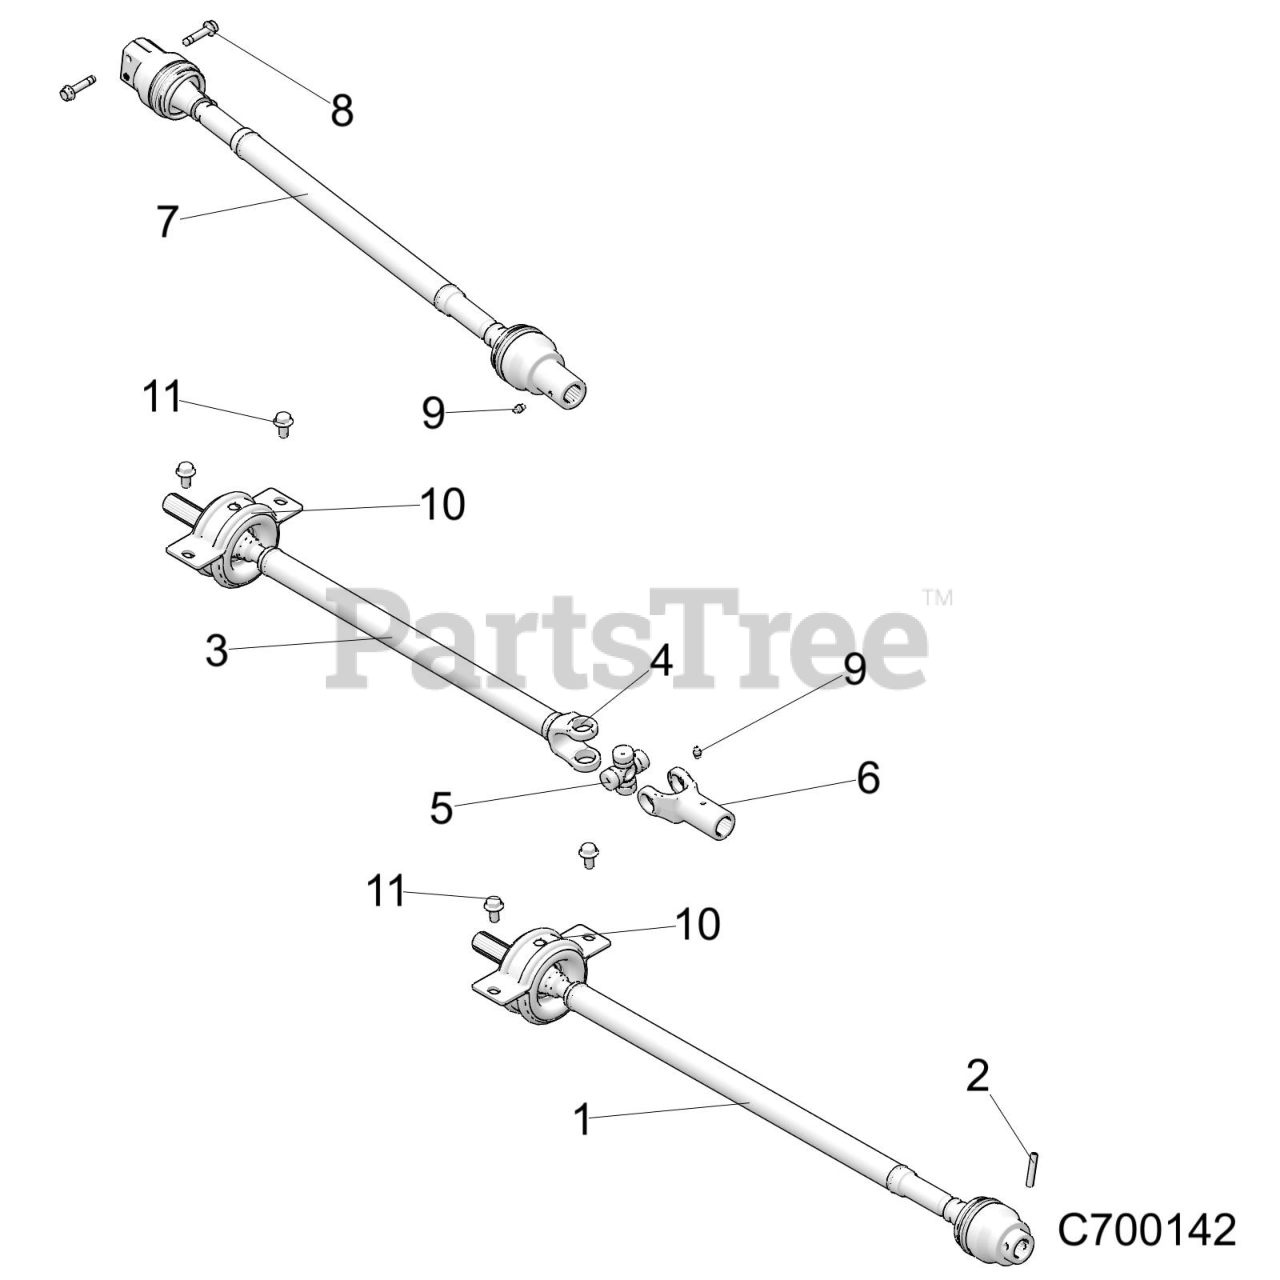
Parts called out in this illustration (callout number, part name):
1	ASM., PROPSHAFT, FRONT
1	ASM-PROPSHAFT,FRONT
2	PIN,SPRING(10)
3	ASM-PROPSHAFT,MID
4	YOKE, WELD
5	U-JOINT-1000 SERIES
6	YOKE, SLIP, INDEXED
7	ASM-PROPSHAFT,REAR
8	SCR-HXFL-M8X1.25X40 8.8 ZODP30
9	FITTING, LUBRICATION
10	ASM-BEARING,FLEX
11	BOLT-M10X1.5X20,HXFLG,W/PATCH
